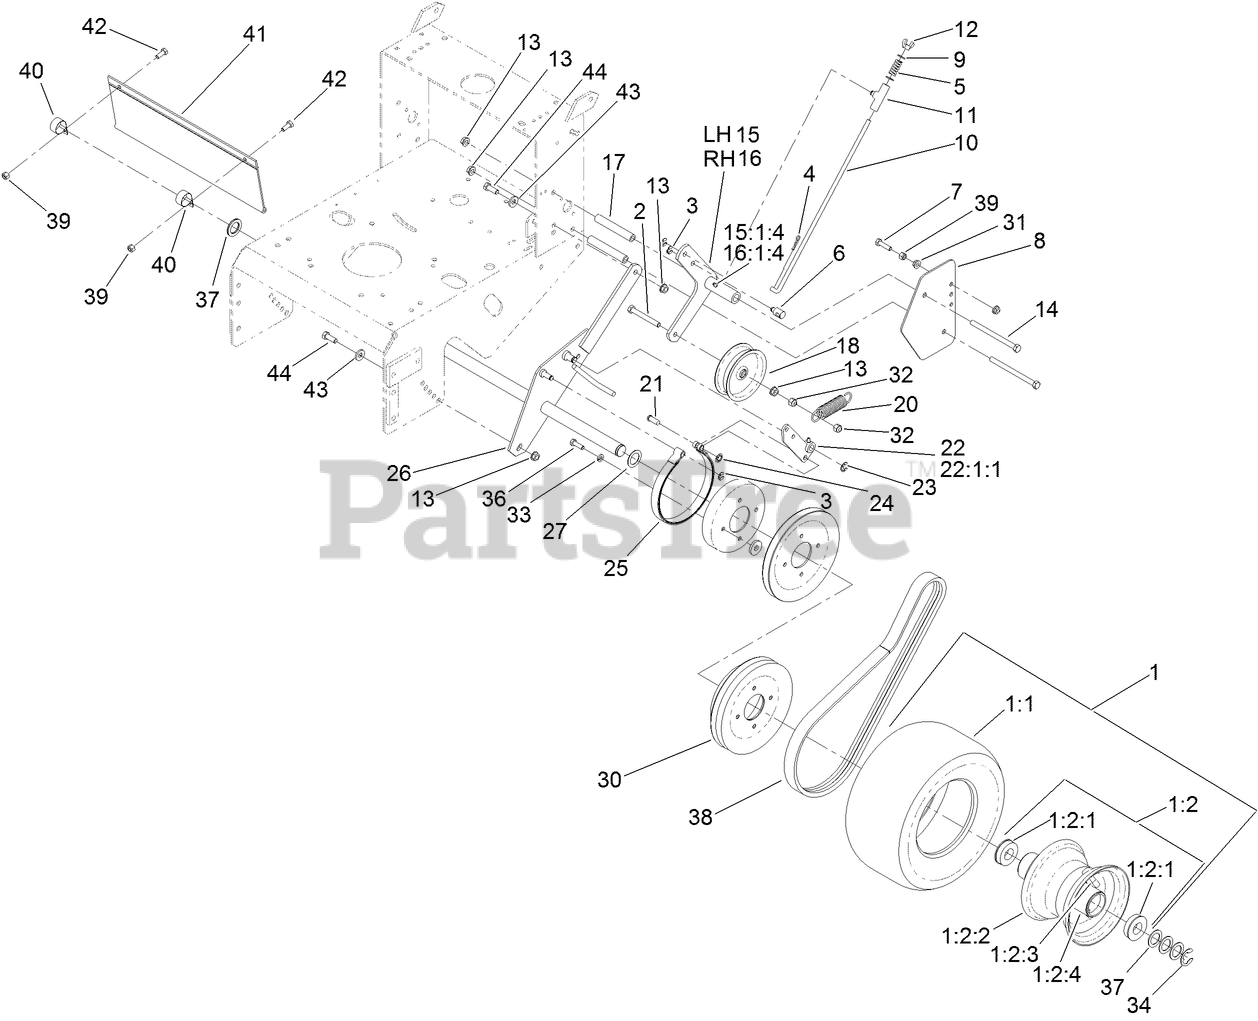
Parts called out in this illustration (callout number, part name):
1	WHEEL AND TIRE ASM
1:1	TIRE
1:2	WHEEL AND HUB ASM
1:2:1	BEARING-FLANGED
1:2:2	Deck ASM
1:2:3	Deck ASM
1:2:4	Deck ASM
2	SCREW-HH
3	RING-RETAINING
4	PIN-COTTER
5	SPRING-COMPRESSION
6	SWIVEL-LEVER, DRIVE
7	SCREW-HH, SPECIAL
8	SHIELD-WHEEL, DRIVE
9	WASHER-PLAIN
10	LINKAGE-BRAKE
11	SWIVEL-BRAKE
12	WINGNUT-NYLOCK
13	NUT-HHF, WHIZ
14	SCREW-HH
15	ARM-IDLER, LH
15:1:4	FITTING-GREASE
16	ARM-IDLER, RH
16:1:4	FITTING-GREASE
17	SPACER-SHIELD
18	PULLEY-IDLER
20	SPRING-EXTENSION
21	PIN-CLEVIS
22	ARM-BRAKE
22:1:1	BUSHING-ZERK
23	RING-RETAINING, EXTERNAL
24	RING-RETAIN,PUSH,EXT,FLAT
25	BAND-BRAKE
27	WASHER-SPACER
30	DRUM AND SHEAVE ASM
31	NUT-HF
32	NUT-LOCK, NI
33	WASHER-LOCK
34	RING-SNAP
36	SCREW-HH
37	WASHER-SPACER
38	V-BELT
39	NUT-LOCK, NI
40	CLAMP-R
41	SHIELD-TRAILING
42	SCREW-HH
43	WASHER-BELLEVILLE
44	SCREW-HH
